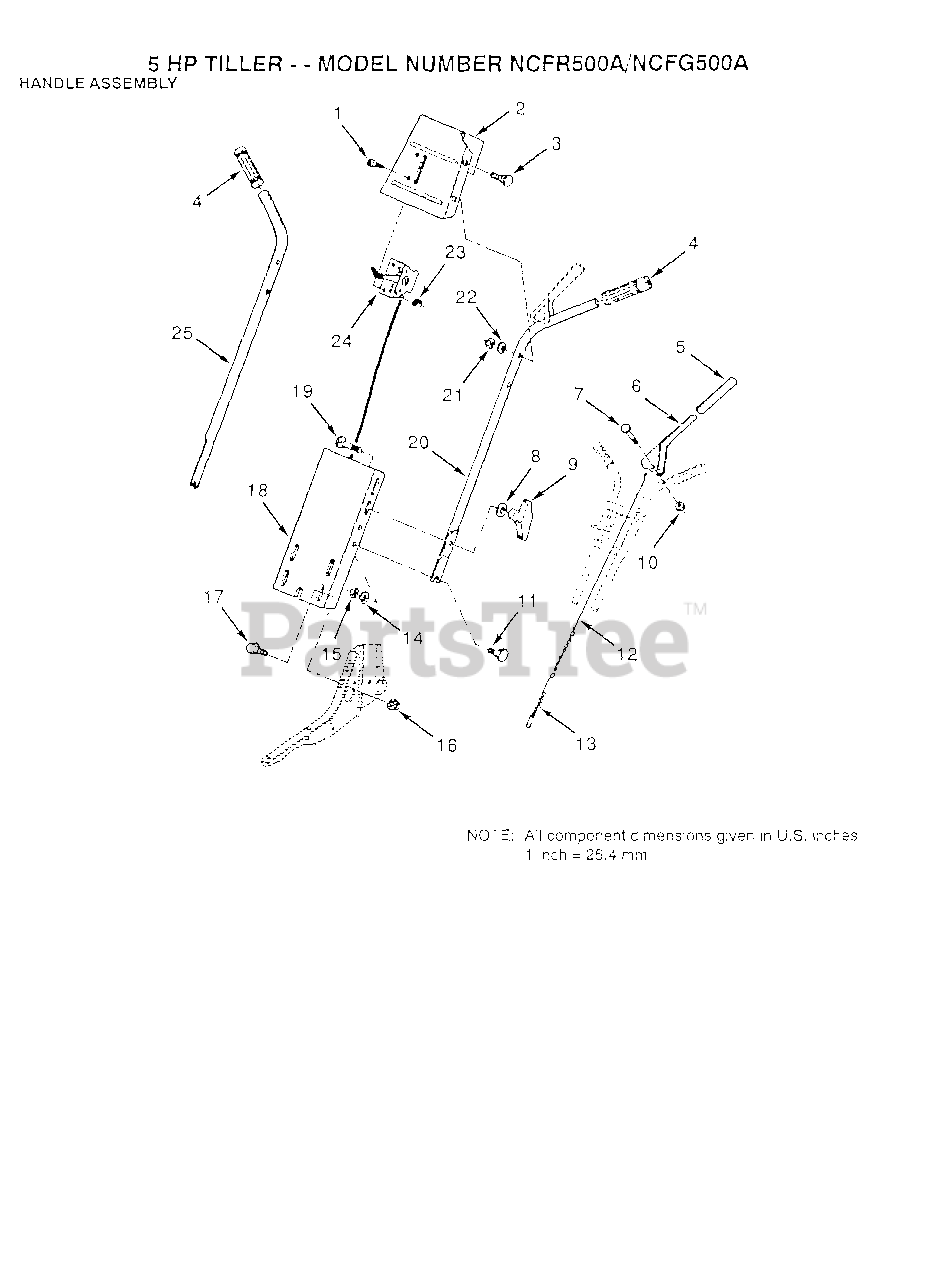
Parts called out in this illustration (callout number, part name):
1	SCREW
2	BRKT HDLE TI
3	BOLT
5	GRIP T
7	BOLT.HEX.5/16-1.5
8	WASHER
13	SPRING EXT TI
14	LOCKWASHER
15	NUT.HEX.5/16-18
16	NUT
17	BOLT
18	"PANEL,HANDLE"
19	BOLT
22	WASHER
